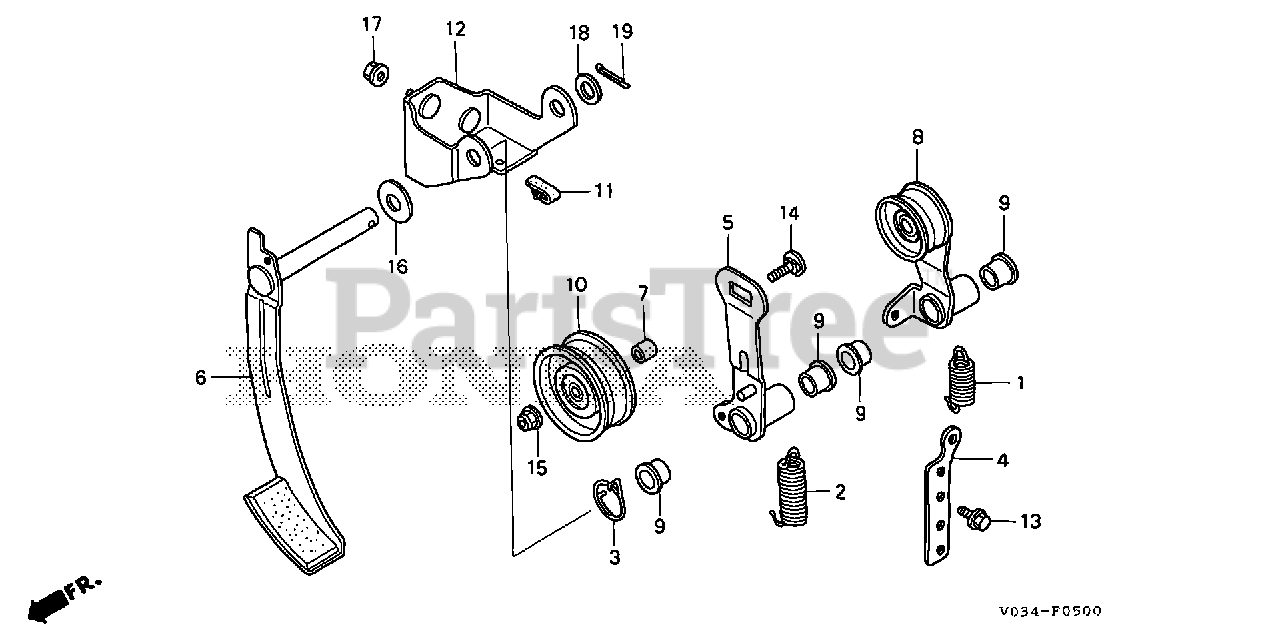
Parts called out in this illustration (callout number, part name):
1	SPRING, WHEEL TENSION RETURN
2	SPRING, AUGER TENSIONER RETURN
3	SPRING, BRAKE ARM
4	STAY, TENSIONER SPRING
5	ARM, AUGER TENSIONER
6	ARM, AUGER BRAKE
7	COLLAR, ROLLER
8	ARM, WHEEL TENSIONER
9	BUSH, TENSIONER ARM
11	RUBBER, STOPPER
12	BRACKET, TENSION ARM
13	BOLT, FLANGE (6X12) (CT200)
14	BOLT, ROLLER
15	NUT, SELF-LOCK (8MM) (CLINCH)
16	WASHER, BRAKE ARM
17	NUT, FLANGE (8MM)
18	WASHER, PLAIN (12MM)
19	PIN, SPLIT (3.0X18)
